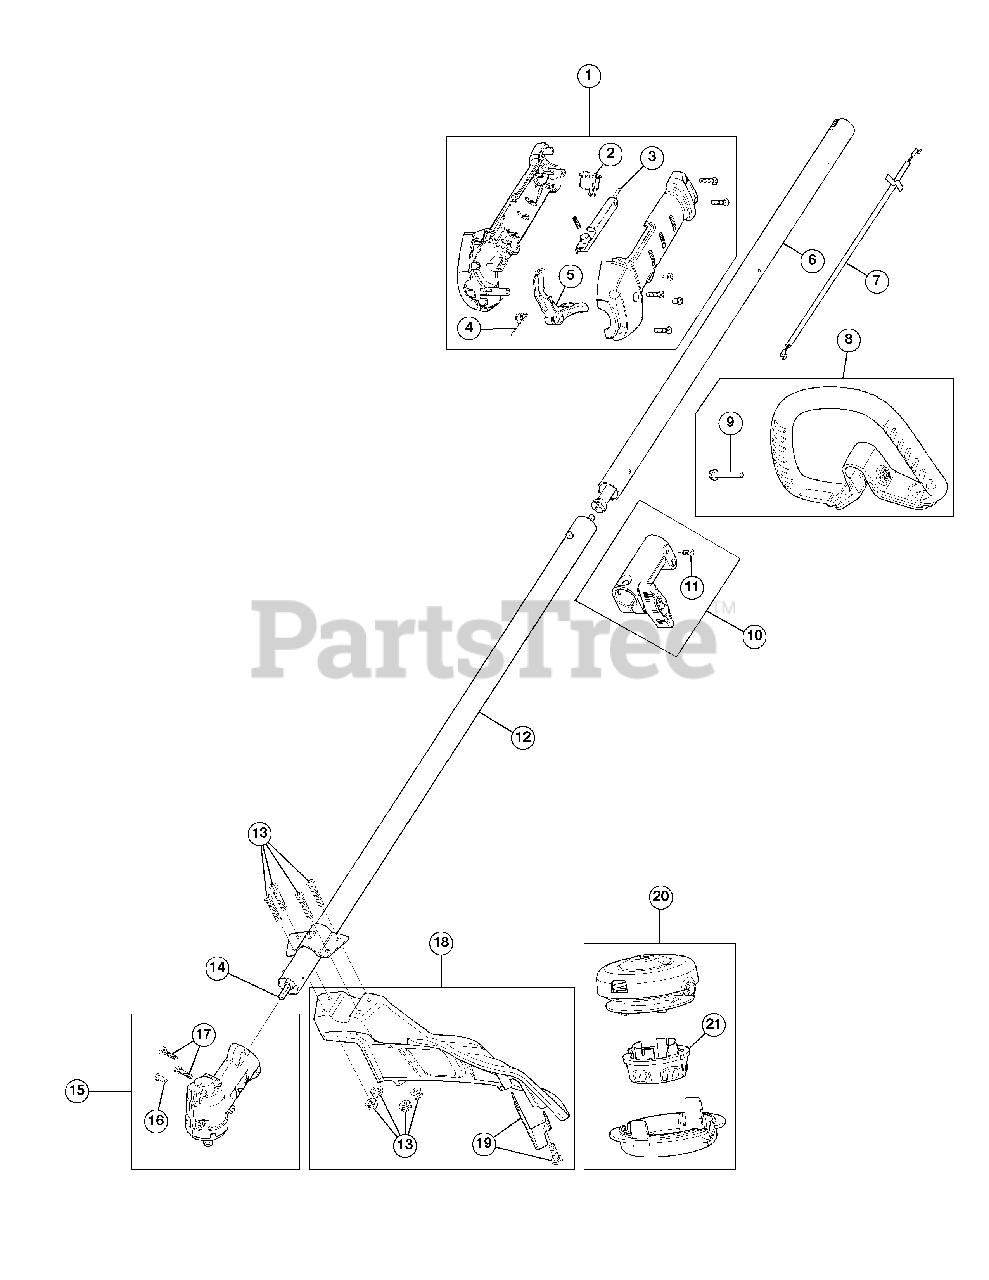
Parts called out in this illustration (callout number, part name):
1	Throttle Housing Assembly (Incl. 2 - 5)
2	Trigger Switch Assembly
3	Throttle Lock-out
4	Throttle Trigger Spring
5	Throttle Trigger
6	Upper Drive Shaft Assembly
7	Throttle Cable
8	D-Handle Assembly (Incl. 9)
10	Split Boom Coupler (Incl. 11)
11	Coupler Anti-Rotation Screw
12	Lower Drive Shaft Housing Assembly
13	Shield Mounting Screws and Nuts
14	Lower Flexible Drive Shaft
15	Gearbox Assembly (Incl. 16 - 17)
16	Gearbox Anti-Rotation Screw
17	Gearbox Mounting Hardware
18	Shield Assembly (Incl. 19)
19	Blade Assembly
20	Cutting Head Assembly (Incl. 21)
